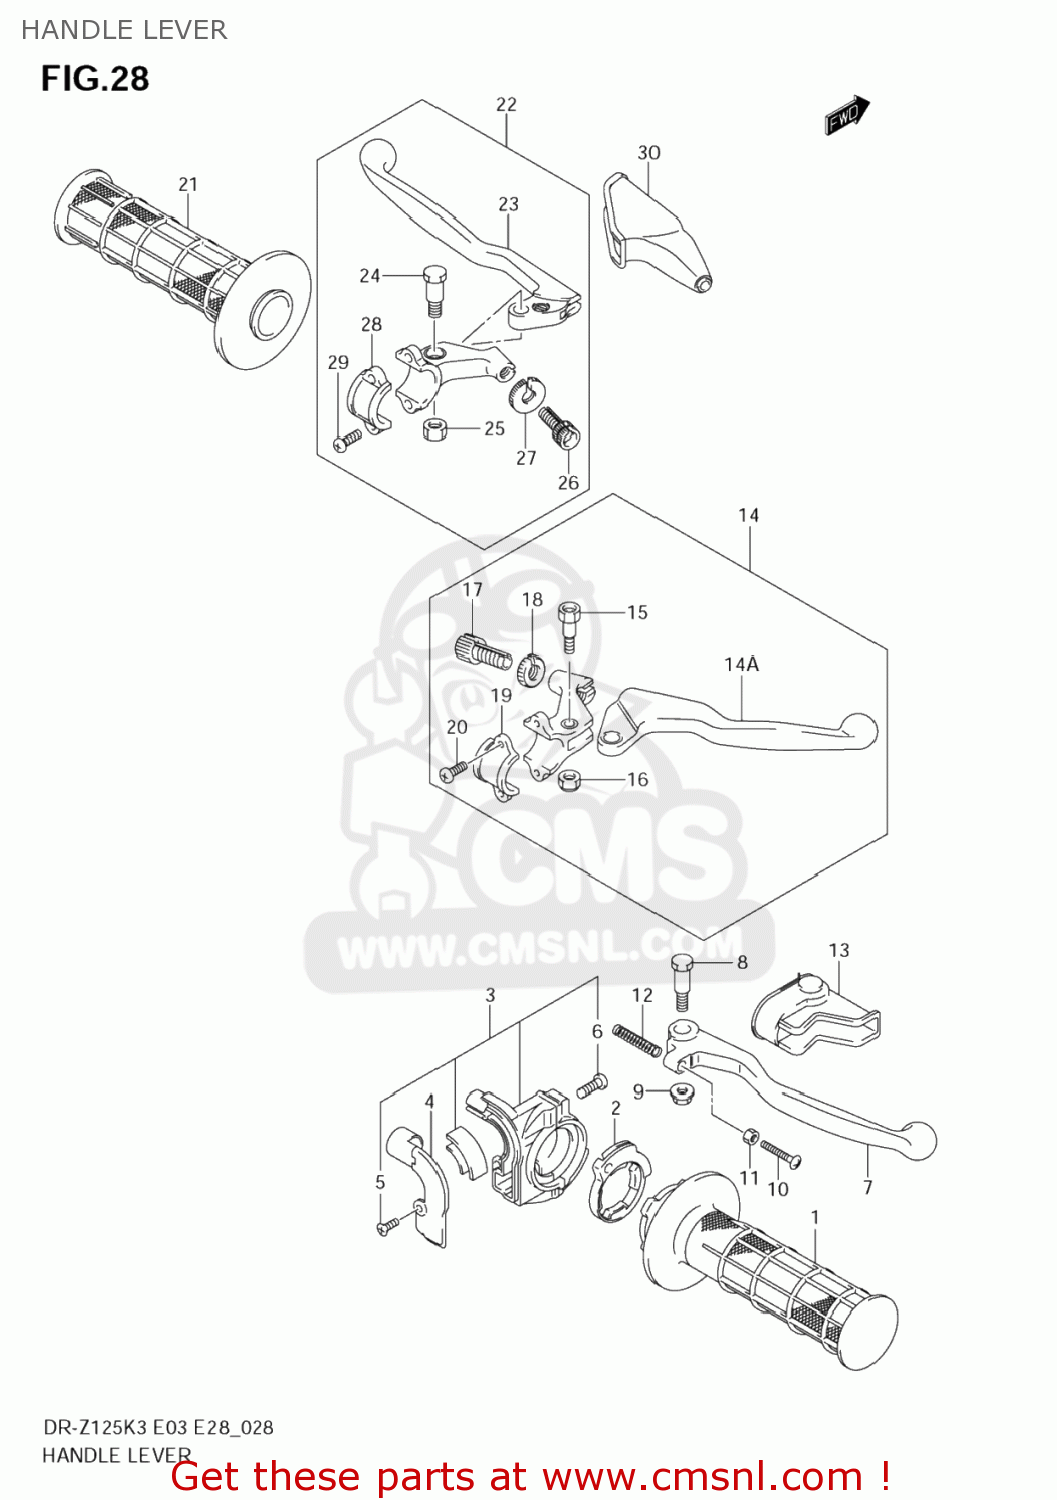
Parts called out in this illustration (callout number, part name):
1	GRIP,THROTTLE
2	ROTOR,THROTTLE GRIP
3	CASE ASSY,THROTTLE
4	COVER,THROTTLE CASE
5	SCREW,UPPER
6	SCREW
7	LEVER,BRAKE
8	BOLT,BRAKE LEVER
9	NUT
10	BOLT,ADJUST
11	NUT
12	SPRING,RETURN
13	COVER,BRAKE LEVER
14	LEVER ASSY,BRAKE
14A	LEVER,BRAKE
15	BOLT,LEVER
16	NUT 6MM
17	ADJUSTER,CABLE
18	NUT,CABLE ADJUSTER
19	BRACKET,CLUTCH LEVER HOLDER
20	SCREW
21	GRIP,L
22	LEVER ASSY,CLUTCH
23	LEVER,CLUTCH
24	BOLT,LEVER
25	NUT 6MM
26	ADJUSTER,CABLE
27	NUT,CABLE ADJUSTER
28	BRACKET,CLUTCH LEVER HOLDER
29	SCREW(5X14)
30	COVER,CLUTCH LEVER
